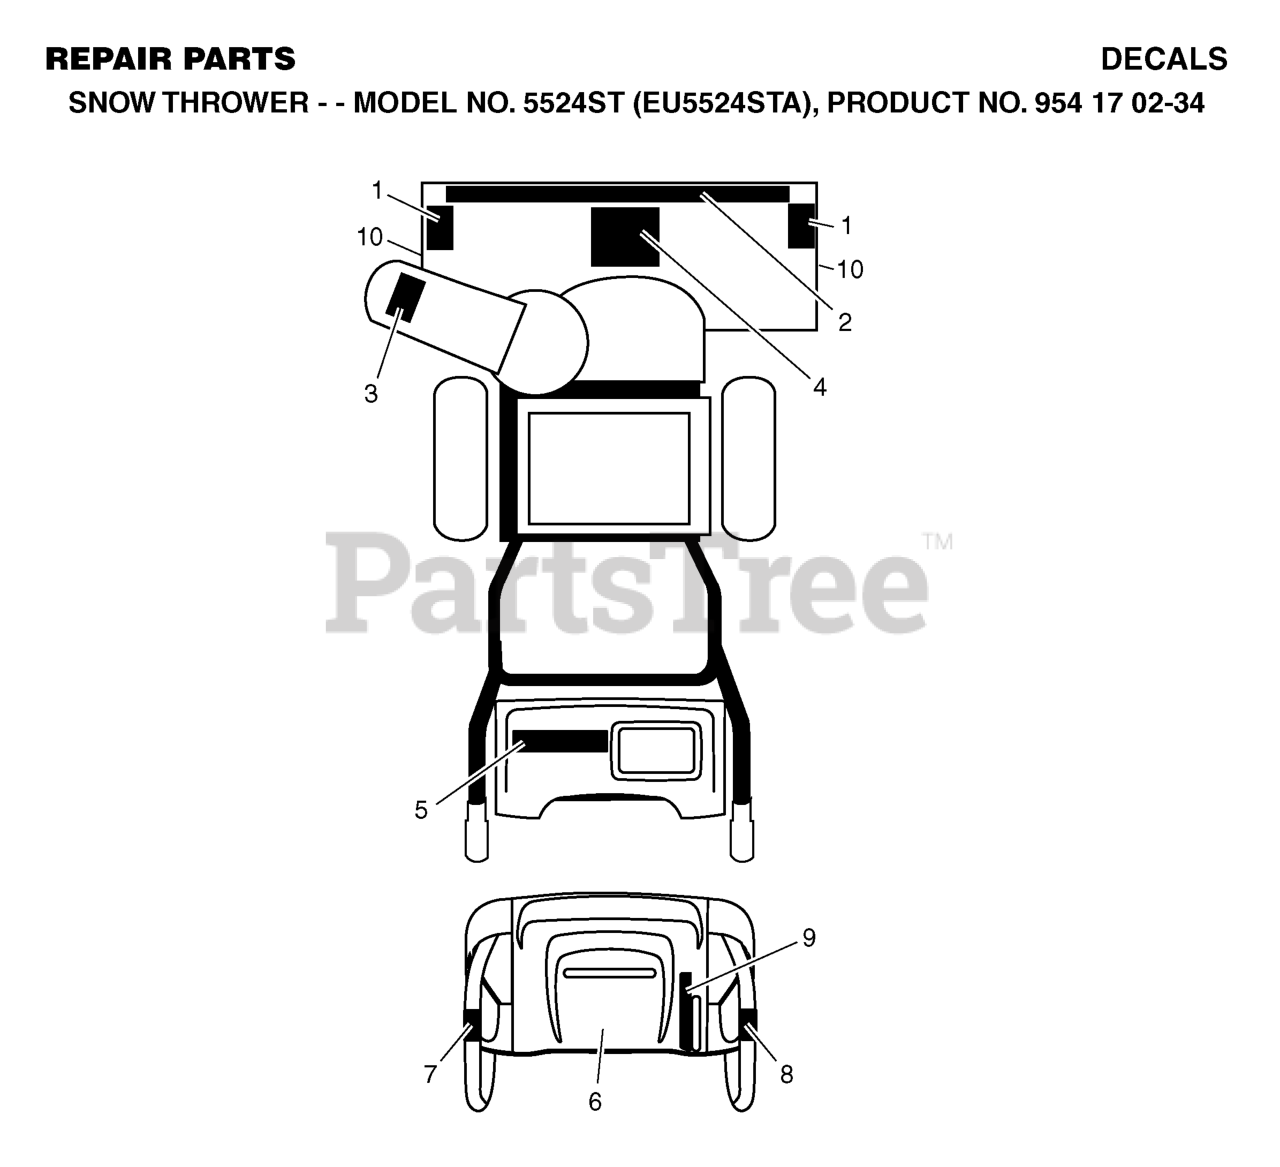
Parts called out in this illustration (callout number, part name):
4	DECAL.AUGER."
6	DECAL.CONSOLE.INSTRUCTION
10	DECAL, HUSQVARNA
